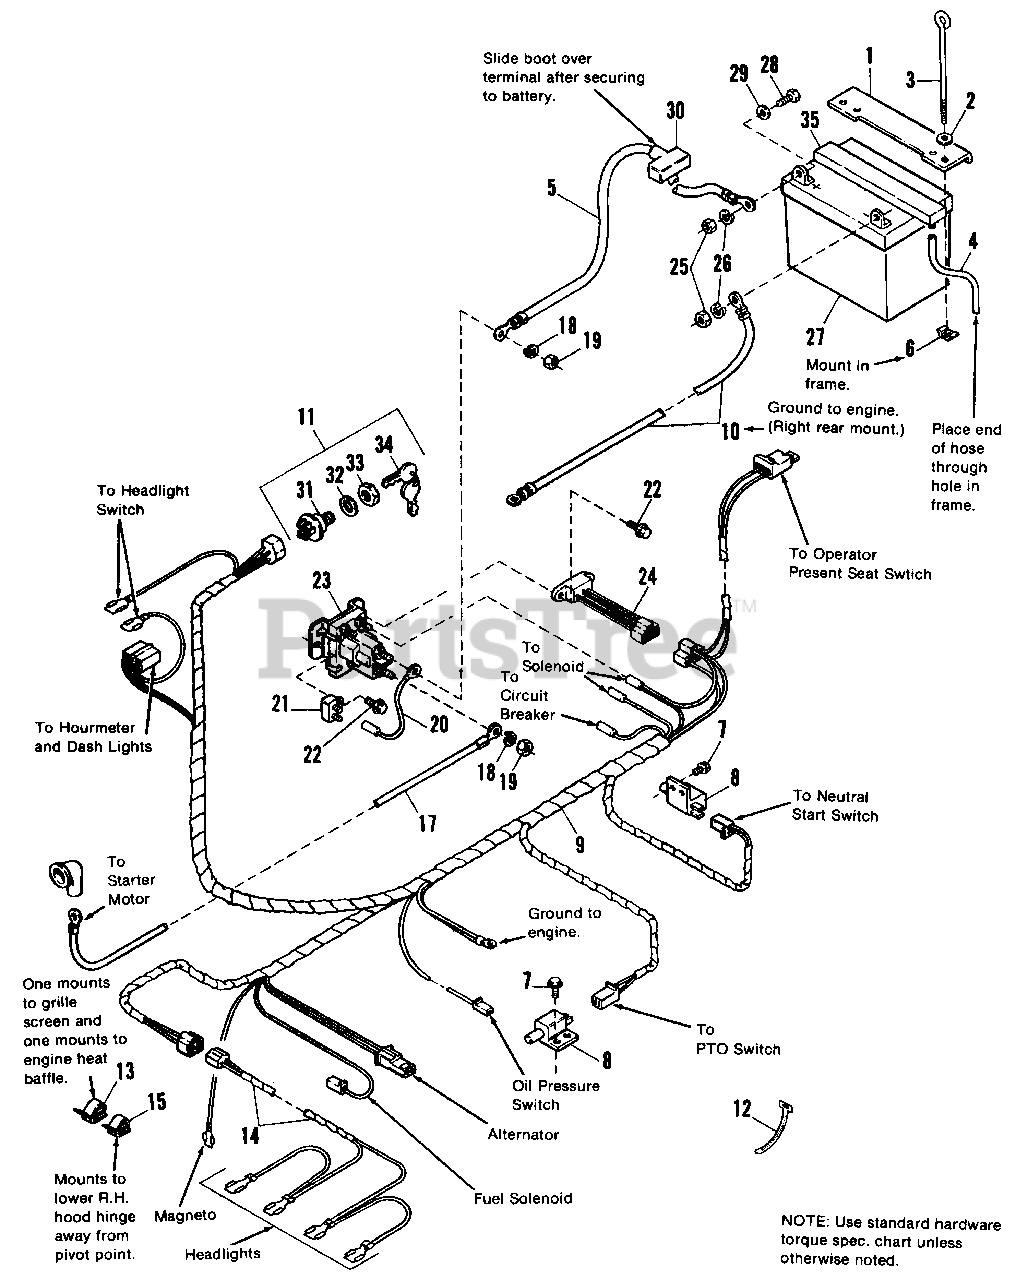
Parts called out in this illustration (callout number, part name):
1	HOLD DOWN, Battery
2	WASHER, 1/4
3	ROD, Battery Hold Down
4	HOSE, Drain, Battery
5	CABLE, Ground
6	NUT, Retainer, 1/4-20
7	SCREW, Taptite, #10-24 x 1/2
8	SWITCH, PTO and Neutral
9	HARNESS, Wiring
10	CABLE, Ground to Engine
11	SWITCH, Ignition (Incl. Ref. Nos. 31, 32, 33 & 34)
13	CLIP, Wire
14	WIRE ASSY., Headlights
16	COVER, Terminal
18	LOCKWASHER, 5/16
19	NUT, Hex, 5/16-24
21	CIRCUIT BREAKER
22	SCREW, Taptite, 1/4-20 x 5/8
23	SOLENOID
24	MODULE, DSI Interlock
25	NUT, Hex, 1/4-20
26	LOCKWASHER, 1/4
27	BATTERY, 39 Amp.
28	CAPSCREW, Hex Hd., 1/4-20 x 3/4
29	WASHER, 1/4 I.D.
30	BOOT, Insulator
32	LOCKWASHER, Internal, 5/8
33	NUT, Hex, 5/8-32
35	VENT, Battery
